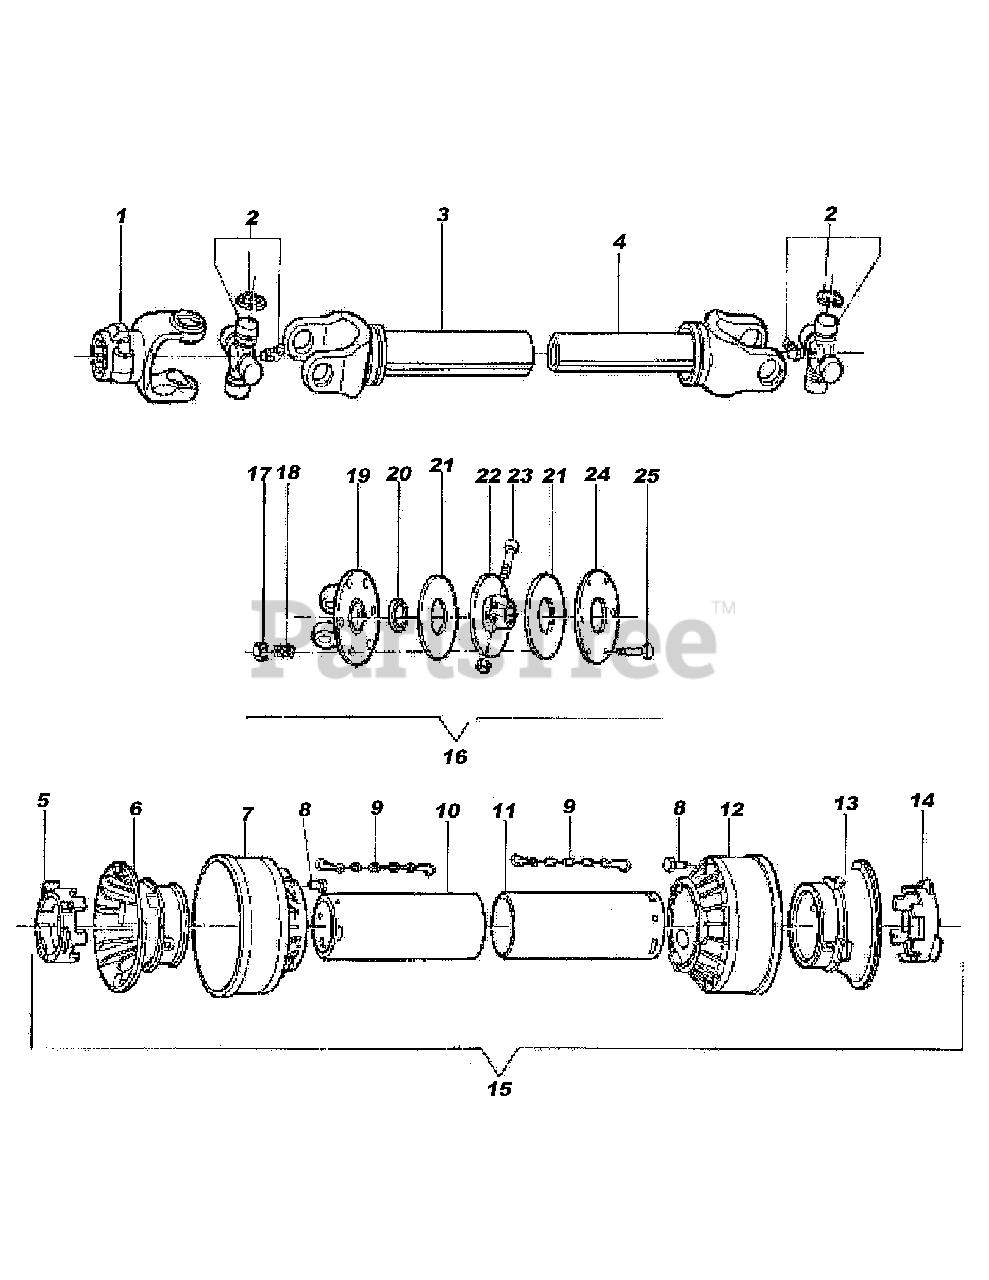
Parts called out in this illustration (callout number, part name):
1	Yoke 1 38/'' 6
2	Cross and Bearing
3	Outer Tube and Yoke
4	Inner Tube and Yoke
5	Yoke Shearbolt
6	Tube Outer Bearing
7	Outer Tube Rigid Cone
8	Soft Cone
9	Pin for Stop Rotation
10	Outer Shield
11	Chain
12	Inner Shield
13	Inner Tube Rigid Cone
14	Tube Bearing Inner
15	Shield Complete
16	Slip Clutch Yoke Complete
17	Bolt M10 x 80
18	Dirt Shield
19	Nut 10MM Nylock
20	Spring
21	Yoke Slip Clutch
22	Friction Disk
23	Spacer
24	Body Friction Clutch
25	Bolt mM12 65 with Nut
26	Outer Flange
